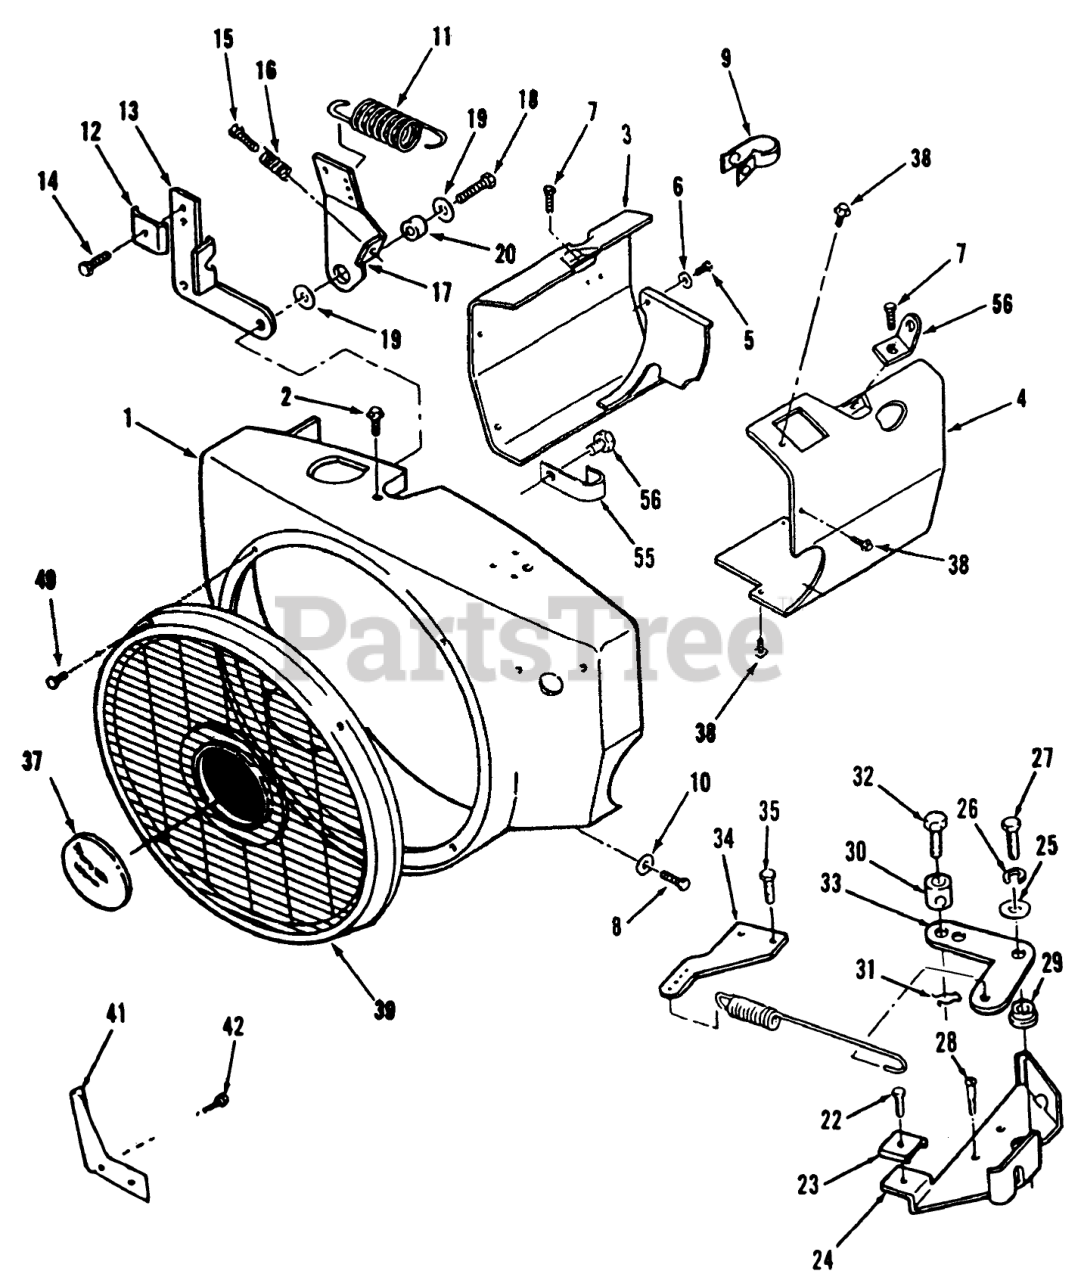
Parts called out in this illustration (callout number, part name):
1	HOUSING
2	HEX HD CAPSCREW
3	LH AIR CYLINDER HSG
4	RH AIR CYLINDER HSG
5	SCREW-HH
6	Clamp
7	SCREW-HWH
8	Bolt
9	Clamp
10	Washer
11	Spring
13	BRACKET
14	Bolt
15	SCREW-TAP
16	Spring
17	GOVERNOR CONTROL ARM
18	SCREW-HWH
19	Screw
20	Bushing
22	TAPPING HEX HD CS
24	BRKT-GOVERNOR CONTRL
25	WASHER-FLAT
26	WASHER-LOCK, SPRING
27	SCREW - CAP HEX HEAD
28	HEX HD CAP SCREW
29	BUSHING-GOV CONTROL
30	Oil Seal
31	PIN-COTTER
32	Bolt
33	LINK-GOV CONTROL
34	ADAPTER-GOV ARM
35	SCREW-TAPPING PAN HD
37	NAME PLATE LOGO
38	Bolt
39	GUARD-STATIONARY
41	BRACKET
42	SCREW - THREAD CUTTING
49	SCREW-PAN HEAD
55	Clip
56	Bracket-Lifting
